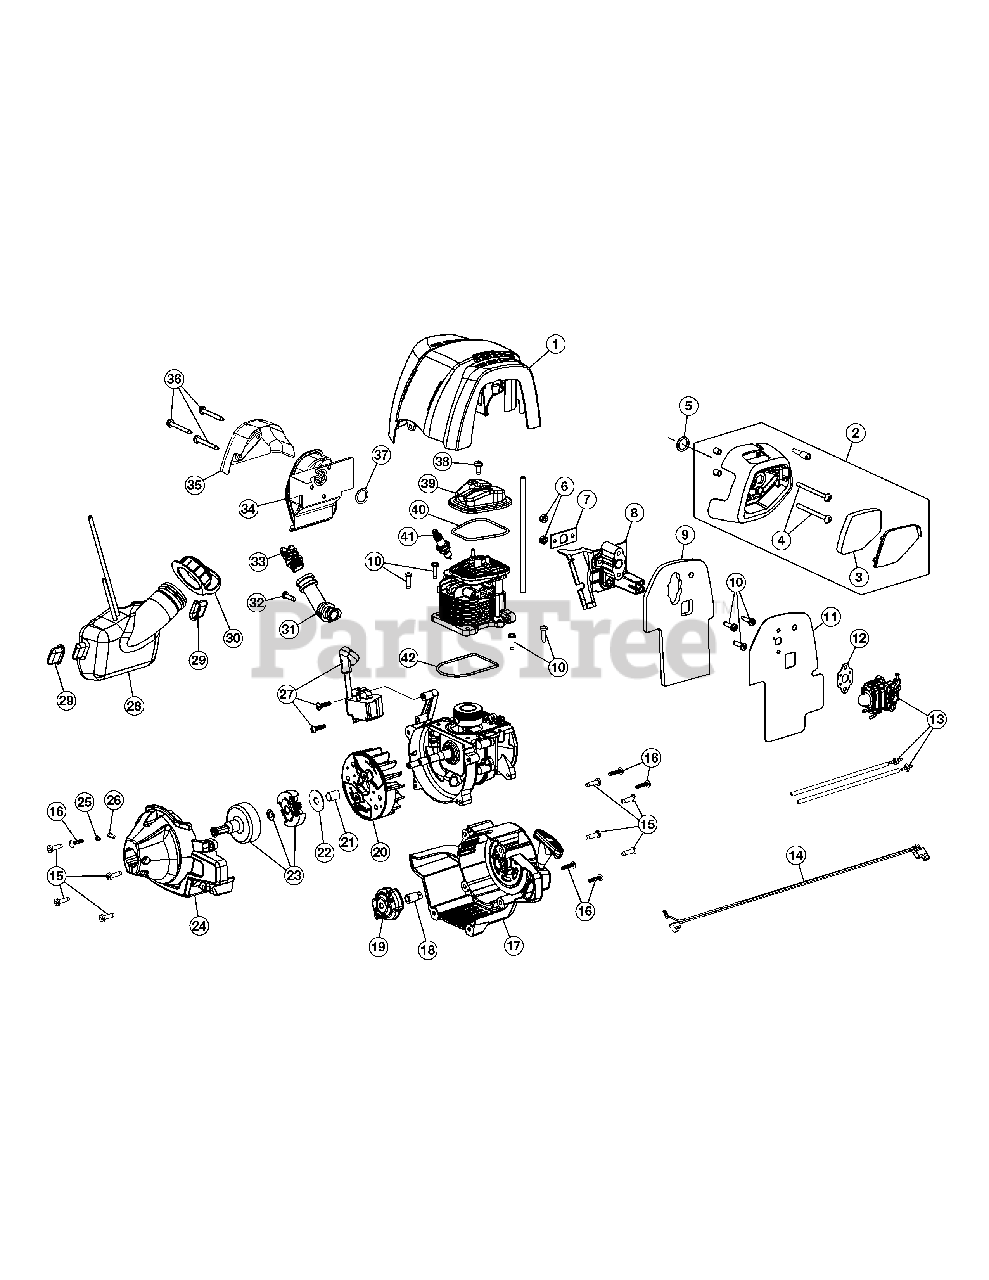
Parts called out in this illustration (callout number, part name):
1	Engine Cover
2	Aircleaner Assembly (Incl. 3 & 4)
3	Air Filter
5	Carburetor O-Ring
7	Insulator Gasket
9	Carburetor Heat Shield
10	Screw
11	Carburetor Baffle
12	Carburetor Gasket
13	Carburetor Assembly (with Fuel Lines)
17	Starter Cover Assembly
18	Electric Start Adapter
19	Pawl Assembly
22	Clutch Washer
23	Clutch Assembly
24	Clutch Cover Assembly
25	Anti-rotation Screw
26	Clamp Screw & Nut
27	Module Assembly
28	Fuel Tank (Incl. 32)
30	Fuel Tank Pad
31	Oil Fill Tube Assembly
33	Oil Plug Assembly
34	Muffler Assembly
35	Muffler Shield
36	Muffler Bolt
37	Muffler Gasket
39	Valve Cover
40	Valve O-Ring
41	Spark Plug
42	Cylinder O-Ring
